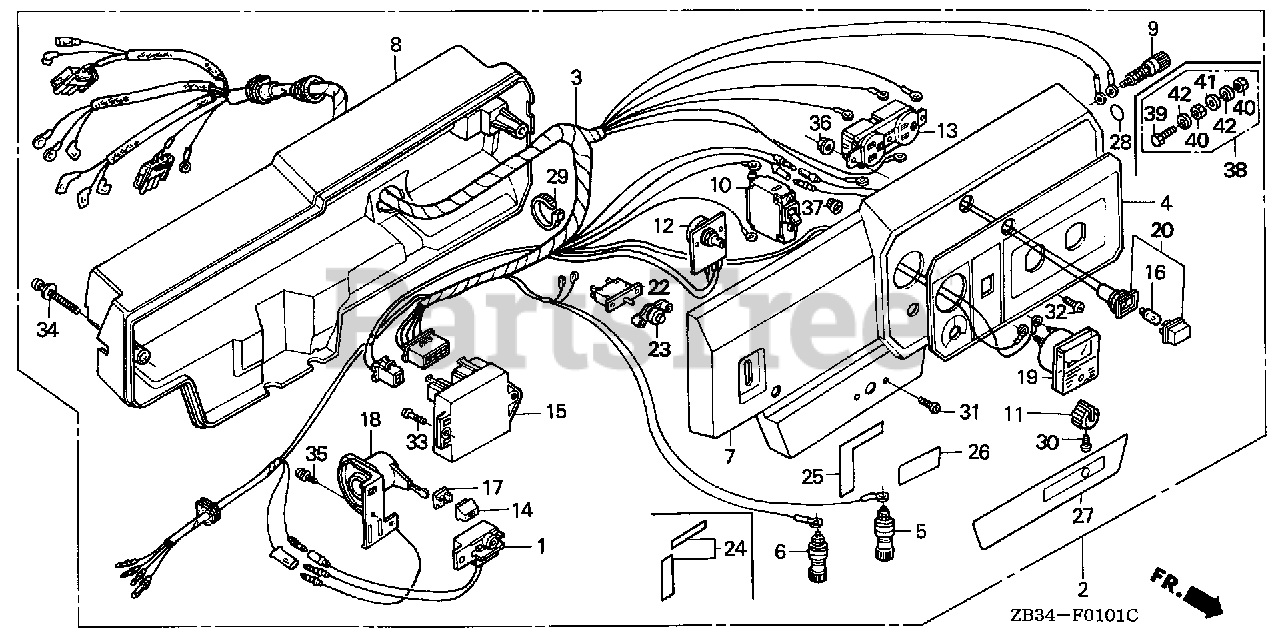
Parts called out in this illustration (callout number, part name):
1	ALERT UNIT, OIL (NOT AVAILABLE)
2	BOX ASSY., CONTROL *R8* (BRIGHT RED)
2	BOX ASSY., CONTROL *R8* (BRIGHT RED) (NOT AVAILABLE)
3	WIRE HARNESS ASSY.
4	MARK, SWITCH PANEL (NOT AVAILABLE)
5	TERMINAL, D.C. OUTPUT (+)
6	TERMINAL, D.C. OUTPUT (-)
7	PANEL, CONTROL *R8* (BRIGHT RED)
8	CASE, CONTROL *R8* (BRIGHT RED)
8	CASE, CONTROL *R280* (POWER RED)
9	TERMINAL ASSY., GROUND
10	BREAKER, CIRCUIT (20A)
11	KNOB, ADJUSTING
13	RECEPTACLE (20A/125V) (MATSUSHITA)
14	KNOB, PETCOCK LEVER
15	REGULATOR UNIT, AUTOMATIC VOLTAGE
16	BULB, WEDGE BASE (12V/2W)
17	BUSH, CONTROL KNOB
18	SWITCH ASSY., ENGINE (STOP SWITCH)
19	VOLTMETER ASSY.
20	SOCKET ASSY., LAMP (GREEN)
22	PROTECTOR, CIRCUIT (D.C.)
23	LENS ASSY., PROTECTOR
25	MARK, ENGINE SWITCH INDICATION
26	MARK, OIL INDICATION
26	MARK, OIL ALERT (ENGLISH)
27	MARK, D.C. OUTPUT
28	MARK, GROUND
29	TIE, CABLE (NATURAL 225X5.0)
30	SCREW, PAN (3X8)
31	SCREW, PAN (3X12)
33	SCREW, PAN (5X8)
34	SCREW-WASHER (6X45)
35	SCREW-WASHER (4X8)
36	NUT, FLANGE (4MM)
